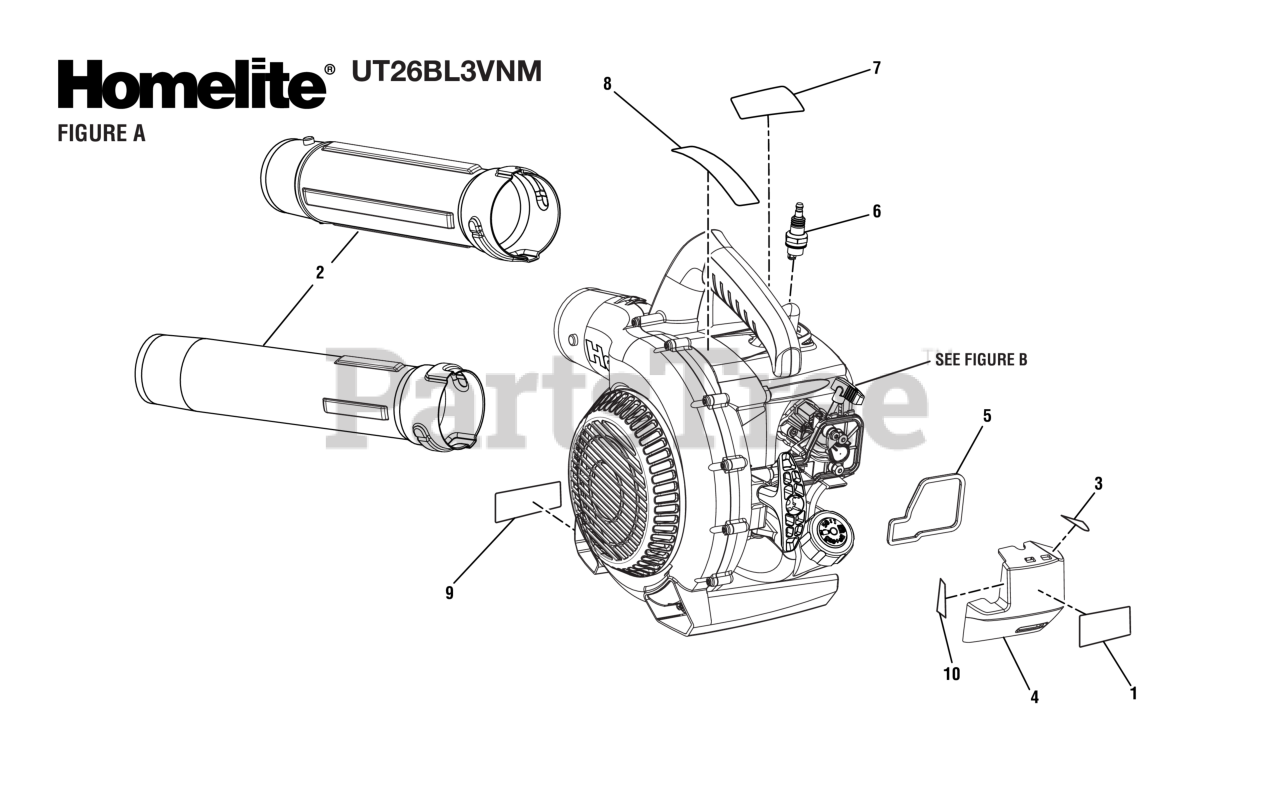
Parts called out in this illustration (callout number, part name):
1	Starting Instructions Label
2	Sweeper Nozzle & Upper Blower Tube Assembly
3	Throttle Label
4	Air Box Cover w/Label
5	Air Box Gasket
6	Spark Plug (Champion RCJ6Y)
7	Logo Label (Engine Shroud)
8	Warning Icon Label
9	Warning Label (Combustion)
10	Choke Label
